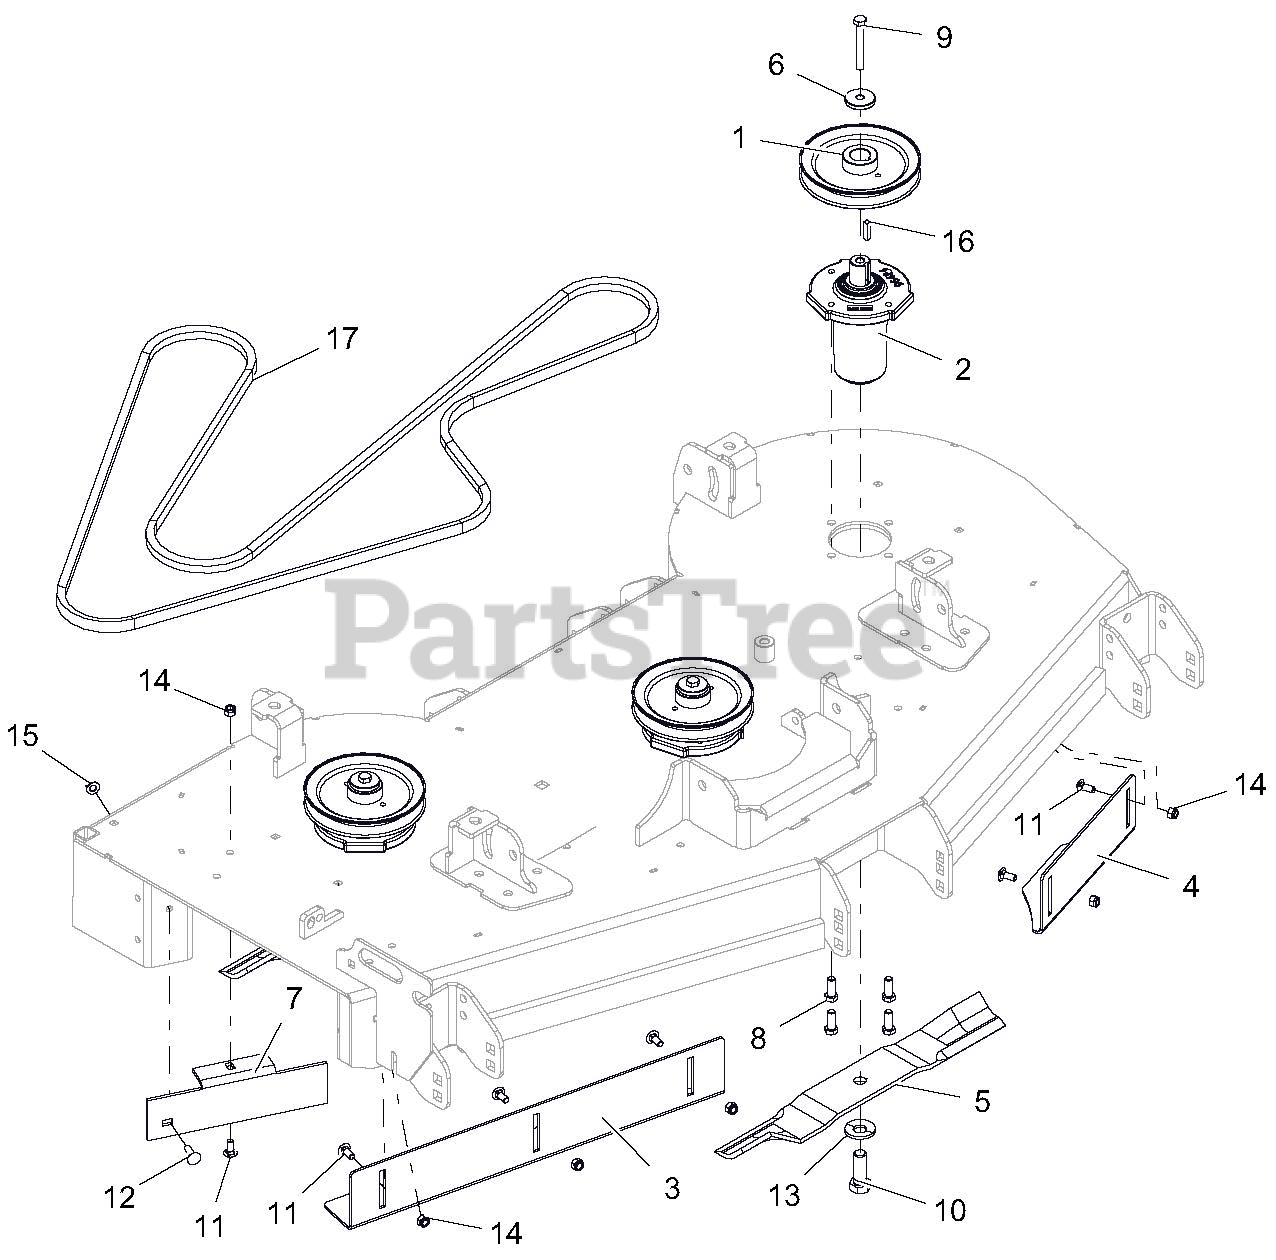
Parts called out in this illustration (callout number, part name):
1	PULLEY, V - 1" ID X 6.00" OD
2	SERVICE, ASM SPINDLE- DUCTILE
3	BAFFLE, 52" RH VACUUM-BLACK
4	BAFFLE, 52" LH VACUUM-BLACK
5	BLADE, 18.00" MOVER (HI-LIFT)
6	RETAINER, SHEAVE SPINDLE
7	BAFFLE, 52 IN DISCHARGE
8	BLT-HEX .38-16X1.00 GR5 YWZC EP30
9	BLT-HEX .38-16X2.75 GR8 YWZC
10	BLT, HEX .62-18X1.75 GR8 YWZC
11	BLT-RDHDSQNK .31-18X.75 G5 YWZC
12	BLT-RDHDSQSHNK .31-18X1.00 G5 Y
13	WSHR, BLVL .63X1.625X.14
14	NUT-LK-NYL .312-18 YWZC
15	NUT-LK-NYL-FLG .31-18 YWZC
16	KEY-SQ .250X.250X1.00 RC 40-50
17	V-BELT, B SECTION RAW EDGE
